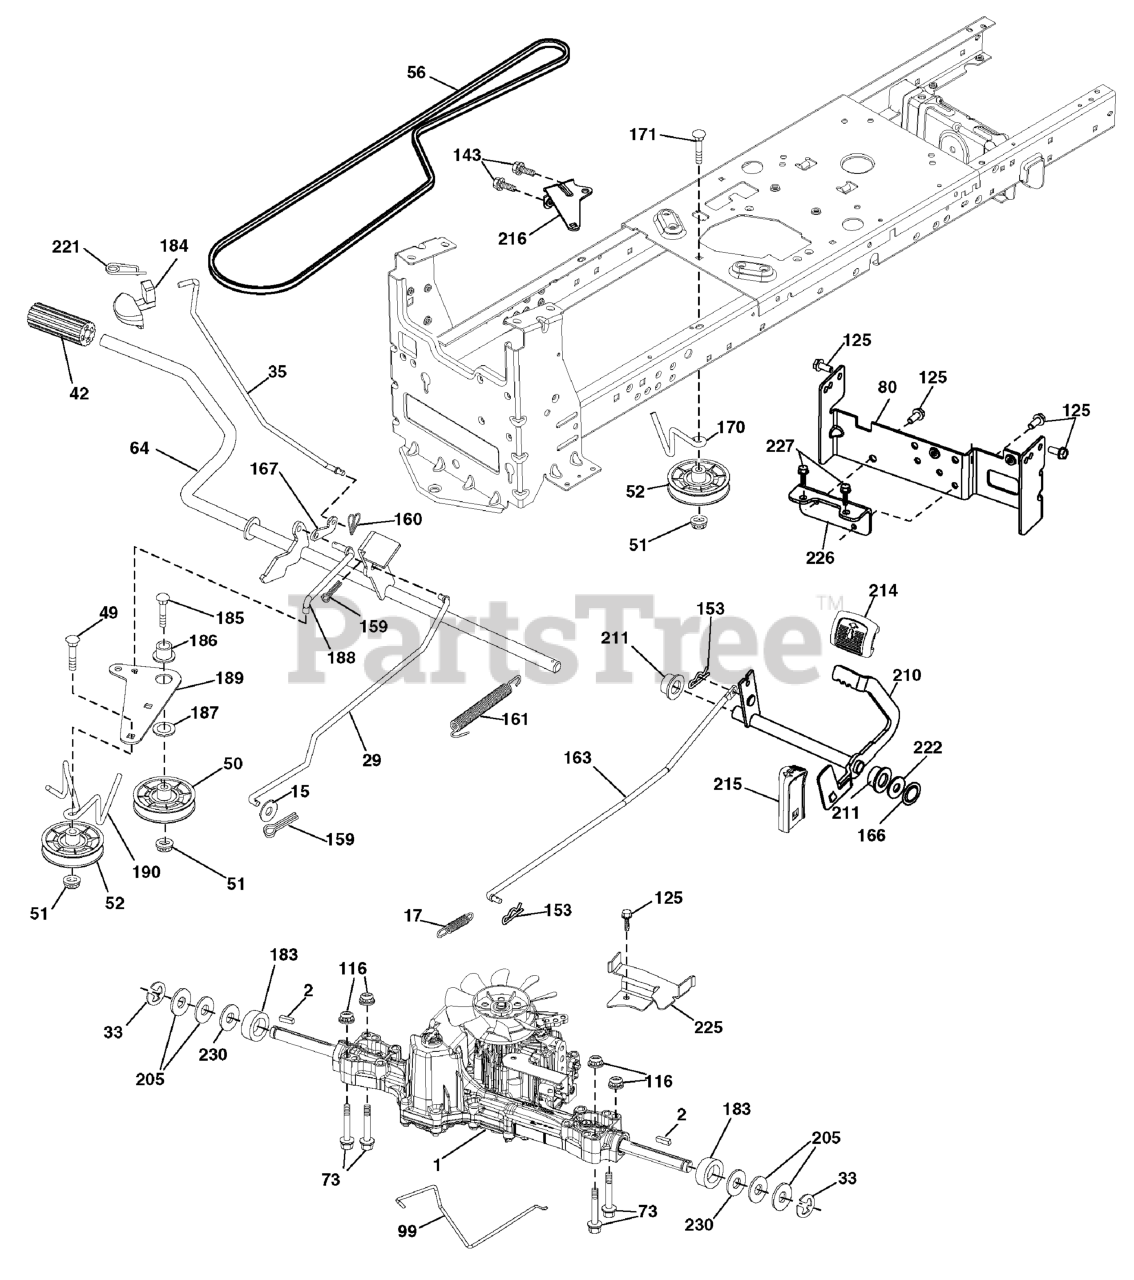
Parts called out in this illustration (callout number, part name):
1	Transaxle, TUFFTORQ K46 BT
2	Key Square
15	Washer 13/32 x 13/16 x 16 Ga.
17	Spring, Brake
29	Rod, Brake
33	Ring E
35	Rod, Brake, Park
42	Cover, Foot Pedal
49	Bolt
50	Pulley Idler Flat
51	Lock Nut 3/8-16
52	Idler V-Groove 910" Offset
56	V-Belt, Drive
64	Shaft Asm. Pedal Brake Control
80	Strap Torque
99	Rod Bypass
116	Nut Lock Hex Flange 5/16-18
125	Screw 5/16-18 x 3/4
153	Retainer Spring
159	Pin Cotter 1/8 x 3/4
160	Retainer Clip
161	Spring, Return, Clutch
163	Rod Control Pedal K46
166	Nut Push .625
167	Latch Brake Parking
170	Keeper Belt Centerspan
171	Bolt RDHD 3/8-16 unc x 2
183	Spacer Split
184	Handle Parking Brake
185	Bolt Rdhd Sqnk 3/8-16 x 2-3/4 Gr.
186	Spacer Retainer
187	Washer
188	Link Clutch Ground Drive
189	Bellcrank Ground Drive
190	Keeper Bellcrank Ground Drive
205	Washer
210	Rocker Asm. Pedal Control
211	Bearing Shaft Brake
214	Pedal Forward Pad
215	Pedal Reverse
216	Bracket Pulley
221	Retainer Spring Clip Handle
222	Washer 21/32 x 1-1/4 10 Ga. N/PLTD
225	Keeper Belt Trans.
226	Bracket Mount Torque
227	Screw 5/16-18 x 3/4
230	Washer Harden
